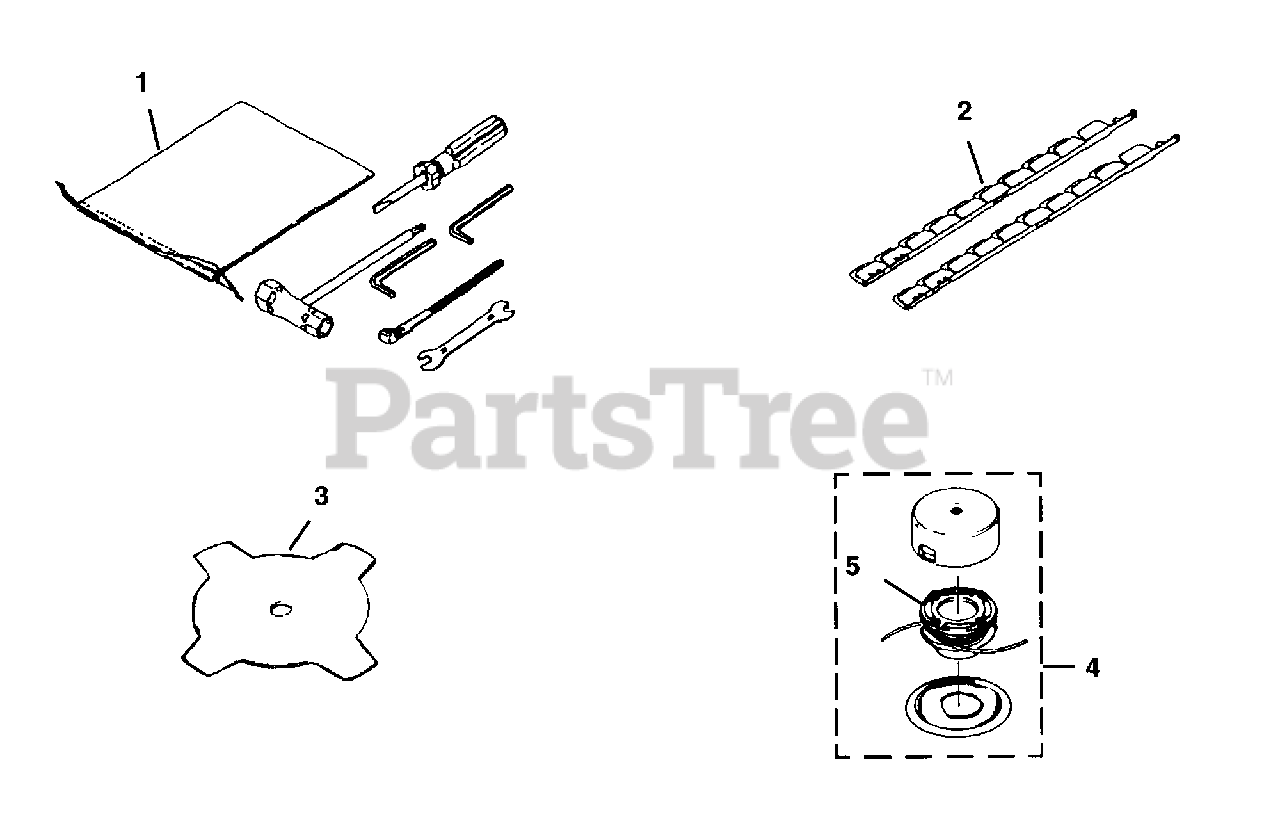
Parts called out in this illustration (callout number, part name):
1	TOOL KIT (BLUE)
2	BLADE COVER
3	BLADE - CUTTER
4	STRING HEAD ASSY
5	SPOOL & STRING
